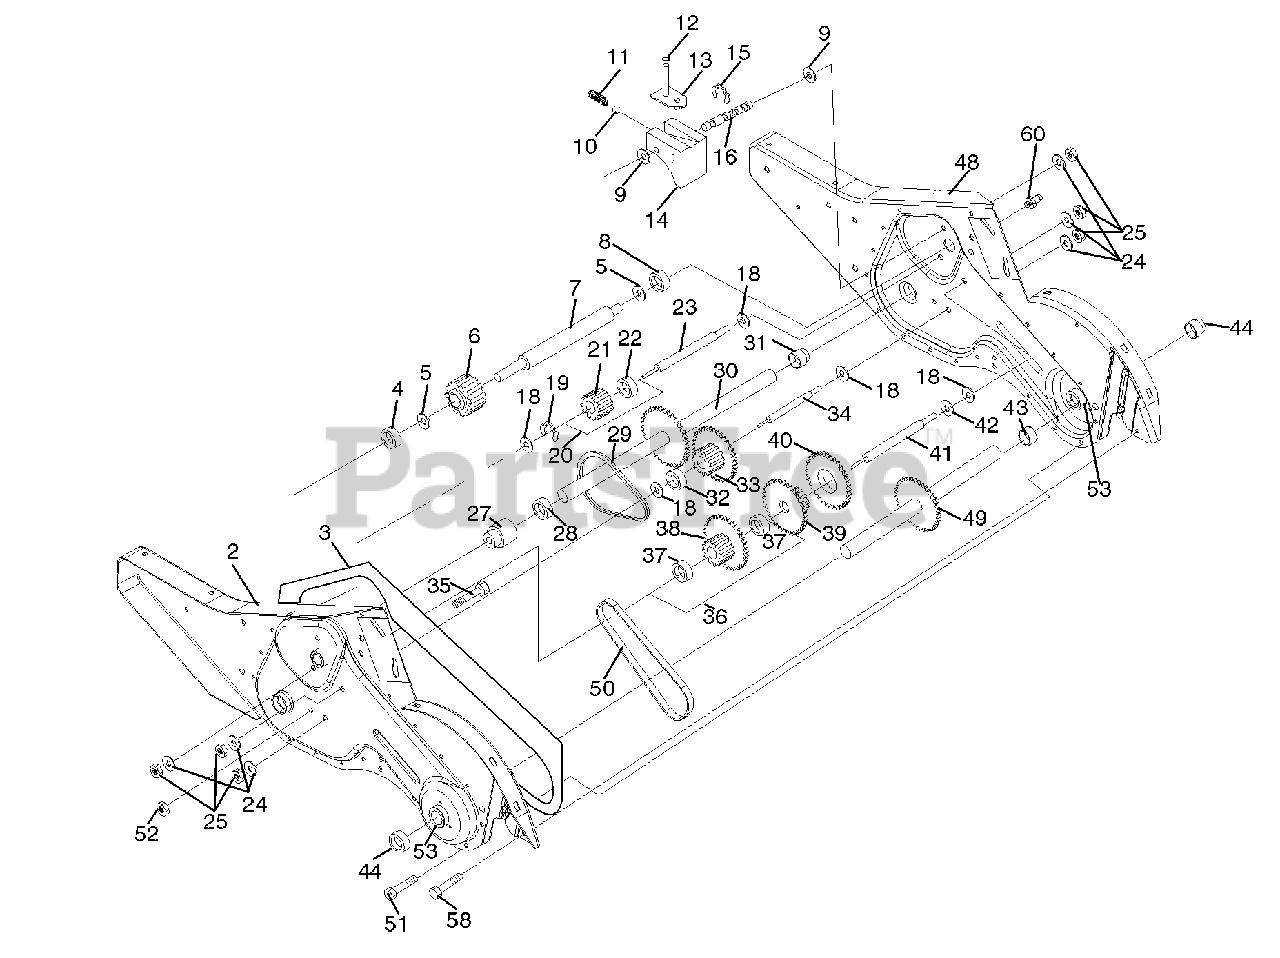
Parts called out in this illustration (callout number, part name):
1	Transmission Assembly
2	Gearcase, L.H. w/Bearing
3	Gasket, Gearcase
4	Bearing, Needle
5	Washer, Thrust 5/8 x 1.10 x 1/32
6	Pinion, Input
7	Shaft, In put
8	Bearing, Needle
9	Washer, Seal
10	Ball, Steel
11	Spring, Shift, Fork
13	Arm, Shift
14	Fork, Shift
15	Ring, Klip
16	Shaft, Shift
19	Ring, Klip
20	Gear, Assembly, Reverse Idler
21	Gear, Reverse Idler
22	Bearing, Needle
23	Shaft, Reverse Idler
24	Washer, Lock 7/16
25	Nut, Hex 7/16-20
27	Bearing, Shaft, Ground Drive L.H.
28	Spacer 0.765 x 1.125 x 1.23
29	Chain #35-50 Pitch
30	Ground Shaft Assembly
31	Bearing, Shaft, Ground Drive R.H.
32	Spacer 0.70 x 1.00 x 1.150
33	Sprocket and Gear Assembly
34	Shaft, Reduction
35	Screw, Whiz, Lock 5/16-18 x 3-1/2
36	Sprocket Assembly w/Bearing
37	Bearing, Needle
38	Sprocket, Tine
39	Gear, Cluster, Red 1st & 2nd
40	Gear, Reverse
41	Shaft, Reduction
42	Washer, Thrust
43	Spacer 1.01 x 1.75 x 0.760
44	Seal Asm, Oil
48	Gearcase, R.H. w/Bearing
49	Shaft, Tine
50	Chain, Roller #50-50 Pitch
51	Screw 1/4-20 x 1/2
52	Nut, Hex 5/16-18
53	Kit, Bearing
58	Bolt Shoulder 1/4-20 unc x .875
60	Fitting Grease
